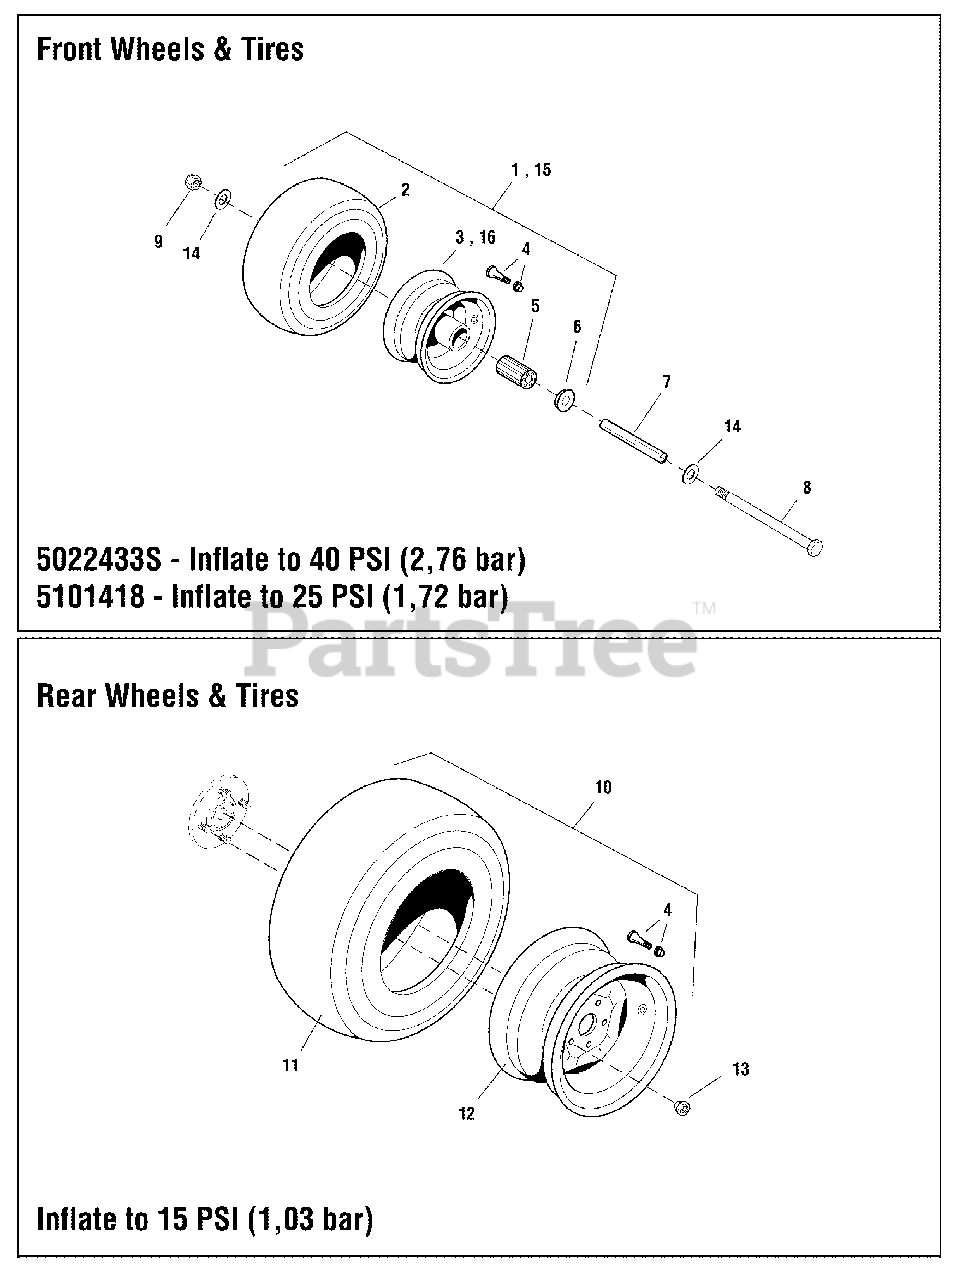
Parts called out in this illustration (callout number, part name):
2	TIRE, FRONT, 11 X 4.0 - 5
3	WHEEL ASSEMBLY, COMPLETE
4	VALVE STEM & CAP ASSEMBLY
5	BEARING, CASTER WHEEL, 11 X 4.0 - 5 BEAD LOCK (SV)
6	BEARING RETAINER
7	AXLE, FRONT CASTER
8	BOLT, 1/2-13 X 6-1/2
9	NUT, HEX NYLON LOCK, 1/2-13
10	TIRE ASSM, 20X8.00-10NHS, TM, 2.625 OFFS
11	TIRE, Rear 20 X 8.0 X 10, TURF MASTER
12	WHEEL, 10 X 7.00 4/4 SOLID F237
13	LUG NUT, 1/2-20
14	WASHER, SAE, 1/2
15	WHEEL, CASTER, 11 X 4.0-5 SILVER BEAD LO
16	WHEEL ASSEMBLY, 11 X 4.0 - 5 TIRE CMP (SV)
